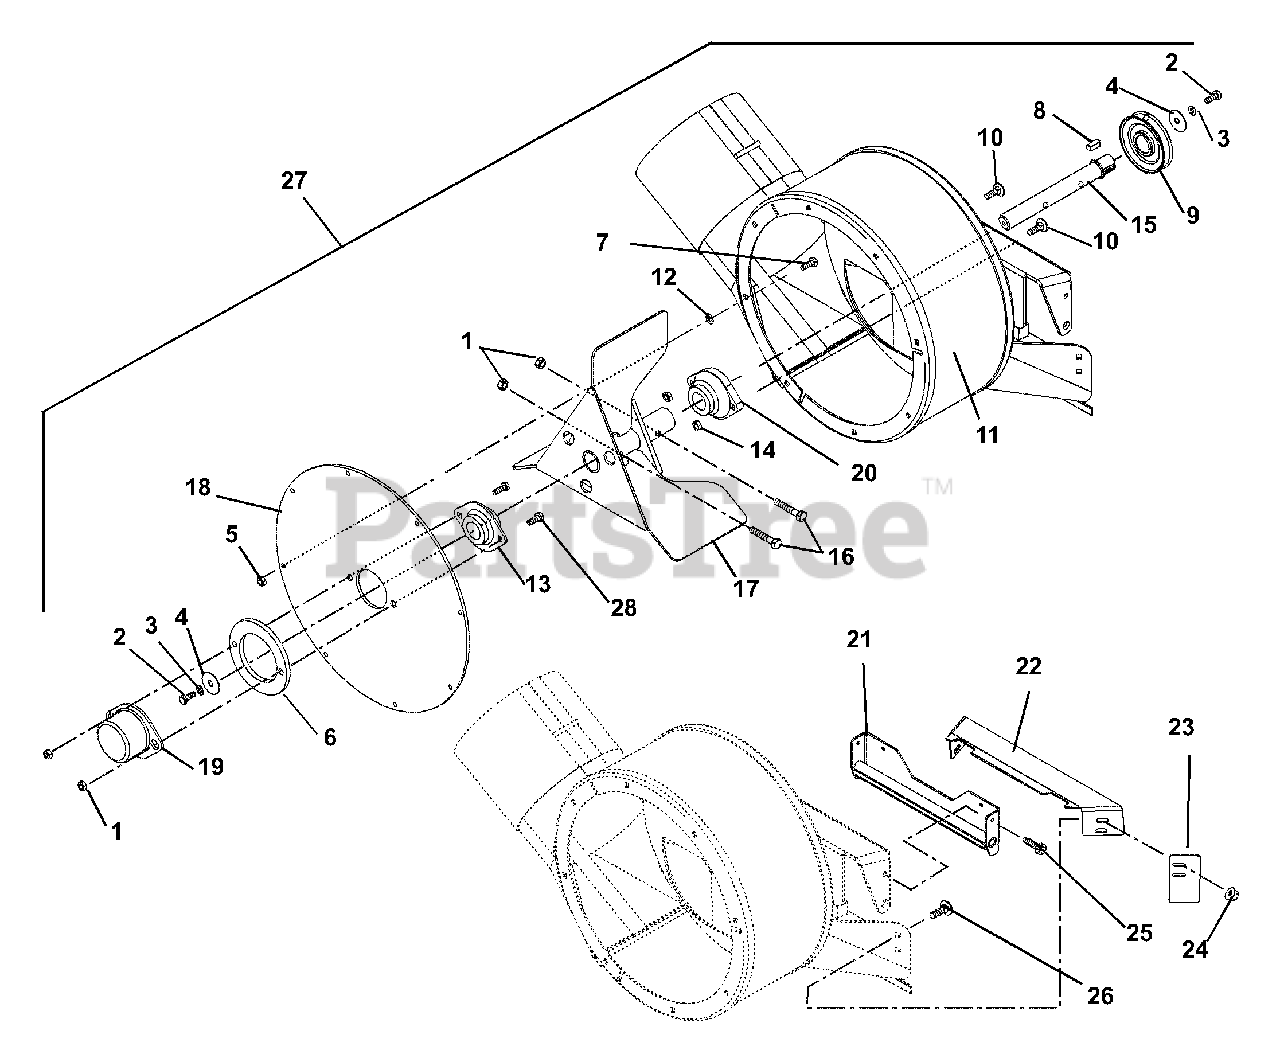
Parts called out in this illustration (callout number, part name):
1	Nut-Locking-Center .31-18
2	Bolt-Hex .25-20 x .75 Grade 5
3	Washer-Locking .25 x .062 Regular
4	Washer-Flat-Steel .265 x 1.370 x .179
5	Nut-Locking-Center .25-20
6	Plate, Retainer
7	Bolt-Round Head Square Neck .25-20 x .50
8	Key-Square .25 x .25 x 1.00
9	Pulley-V 3.50 x 1.004 w/key
10	Bolt-Round Head Square Neck .31-18 x 1.00
11	Weldment, Blower Housing
12	Nut, Push .25 x .50
13	Bearing-2 Bolt x 1.00 Shaft
14	Nut-Locking-Top-Flange .31-18
15	Shaft-Impeller
16	Bolt-Hex .31-18 x 1.75 Grade 5
17	Weldment, Bagger Impeller
18	Cover-Bearing Support
19	Cover-Bearing
20	Bearing, Flange w/Set Screw 1.00 ID
21	Weldment, Blower Mount
22	Guard, Pump Inlet
23	Bar, Extension
24	Nut-Locking-Top-Flange .25-20
25	Screw-Tapping .25-20 x .50 Hex Washer Head Thread Rolling
26	Bolt-Round Head Square Neck .25-20 x .75 Grade 5
27	Assembly, Blower Housing
28	Bolt, Hex .31-18 x 1.0
